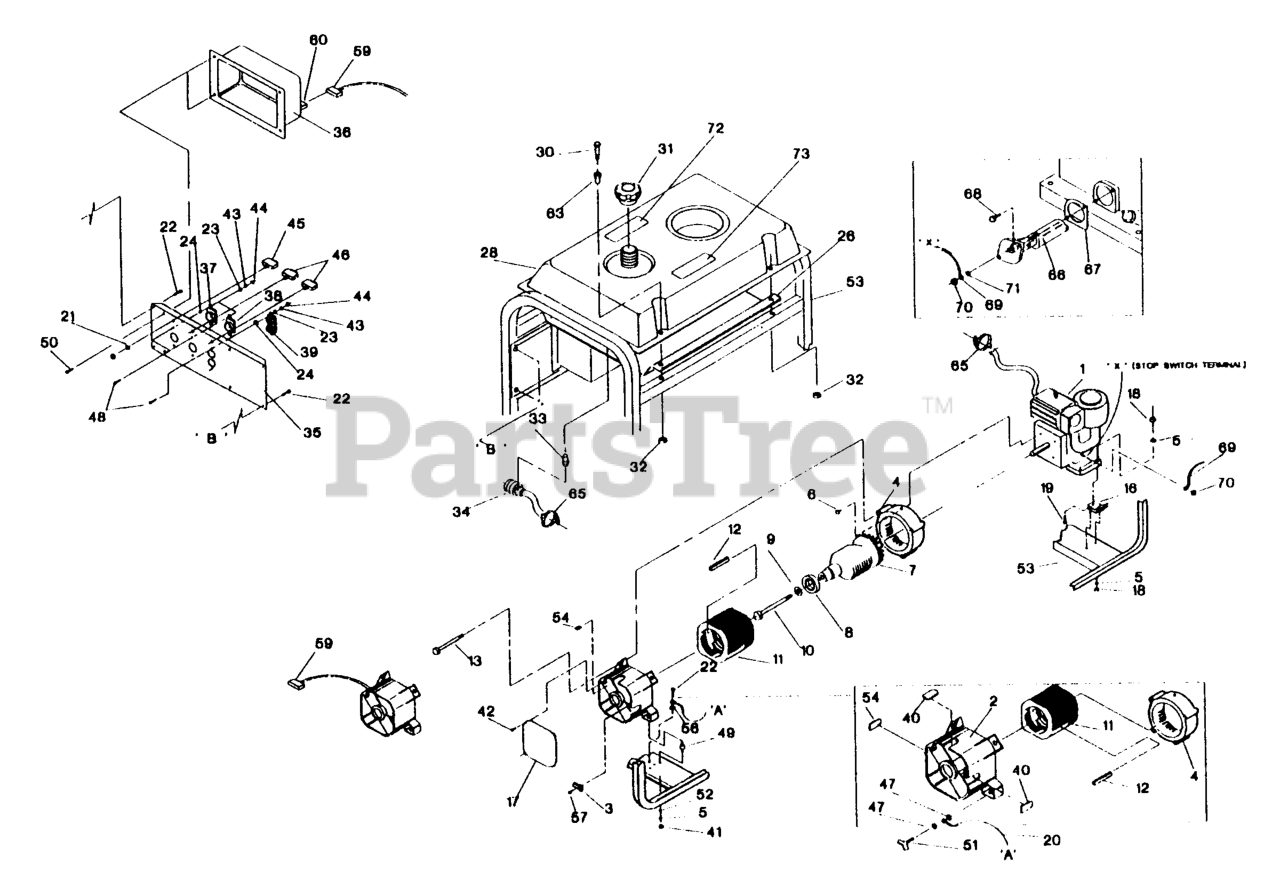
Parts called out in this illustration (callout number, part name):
1	IDLER PULLEY ASSEMBLY
1	BEARING SLEEVE
1	BALL BEARING
2	HEX SCREW 3/8-24 X2.00
3	HEX SCREW 5/16-24 x .62
4	SCREW 3/8-16 x 1.250
5	SCREW 1/4-20 X.500
6	SCREW 1/4-20 x 1.50 GR.5
7	SCREW 1/4-14 x .625
8	SCREW 5/16-18 x .750
9	FLANGE LOCK NUT
10	FLANGE NUT W/HUB
11	PULLEY HUB
12	RETURN SPRING
13	FLAT WASHER .28 ID x .74 OD x .063
14	FLAT WASHER
15	BELL WASHER
16	FLAT WASHER
18	SHOULDER SCREW
19	PIVOT IDLER SPACER
20	SHOULDER SPACER
21	V-BELT FWD DRIVE 4L x 25.375
22	ENGINE PULLEY
23	TRANSMISSION PULLEY
24	CABLE GUIDE ROLLER
25	FORWARD IDLER BRACKET
26	REVERSE IDLER BRACKET
27	CABLE BRACKET ROLLER
28	PULLEY SHIELD
29	FRAME-MOUNT (RH)
30	FRAME-MOUNT (LH)
